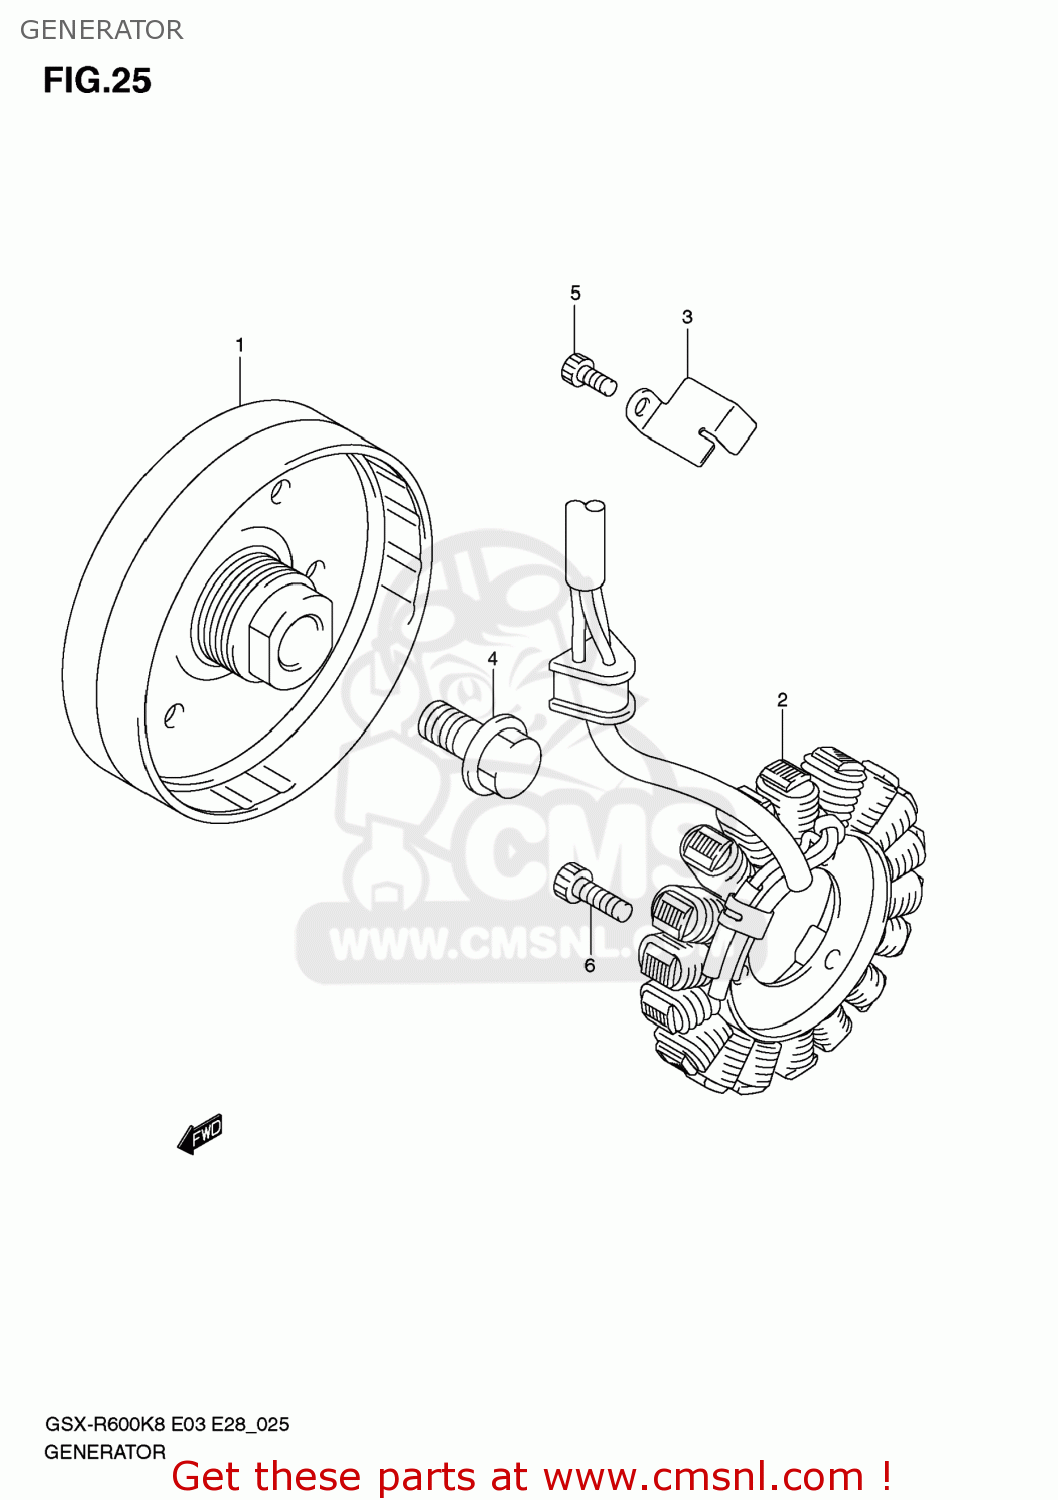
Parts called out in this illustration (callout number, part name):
1	ROTOR ASSY
2	STARTER ASSY
3	CLAMP,MAGNETO LEAD NO.1
4	BOLT(12X23)
5	BOLT
6	BOLT
